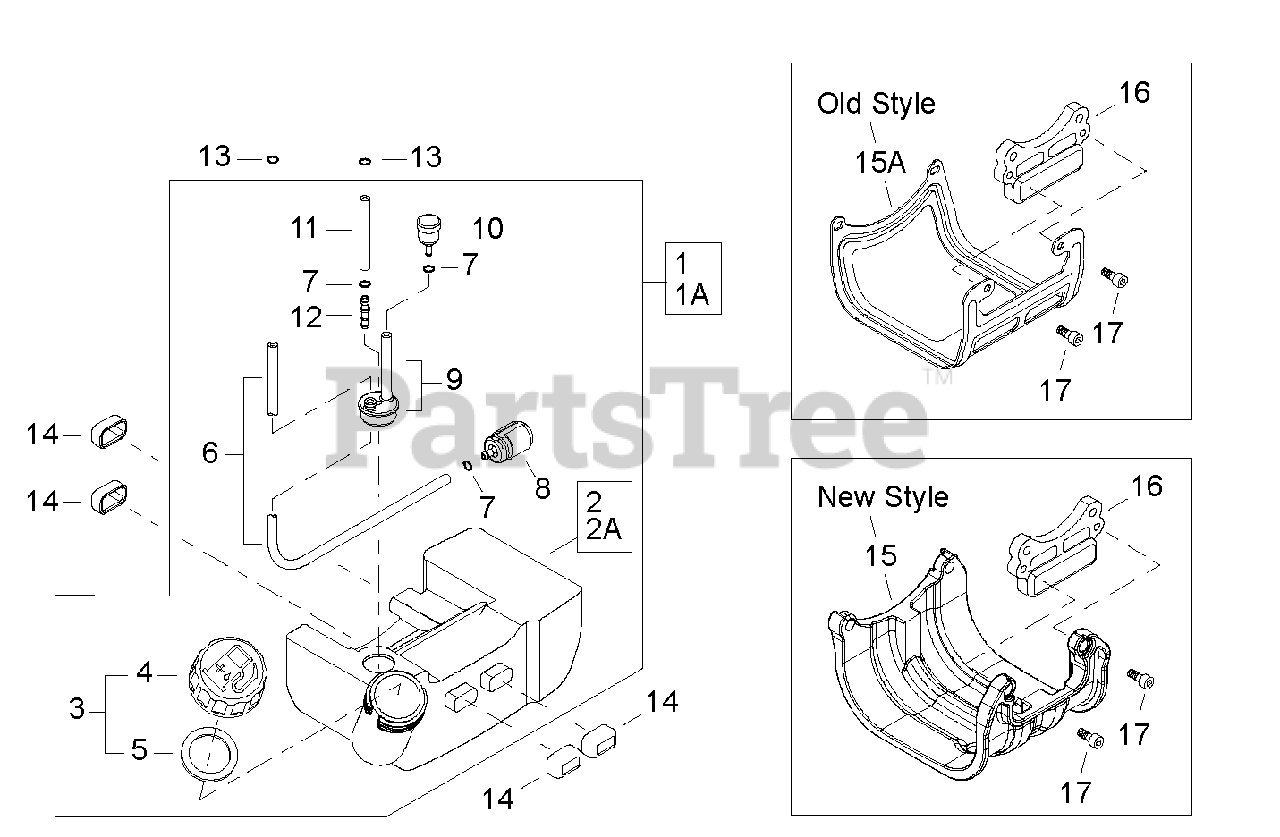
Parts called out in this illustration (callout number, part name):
1	EVC FUEL TANK ASSY
1A	FUEL TANK ASSY
2	EVC FUEL TANK
2A	EPA2 FUEL TANK
3	CAP ASSY
4	CAP, FUEL
5	GASKET, CAP
6	PIPE - FUEL
7	RING, RETAINING - 6
8	FILTER, FUEL
9	GROMMET
10	VENT, FUEL TANK
11	PIPE
12	CONNECTOR, PIPE
13	RING, RETAINING - 6
14	CUSHION, TANK
15	GUARD, FUEL TANK
15A	GUARD, FUEL TANK
16	BRACKET, FUEL TANK
17	SCREW - 5X16
